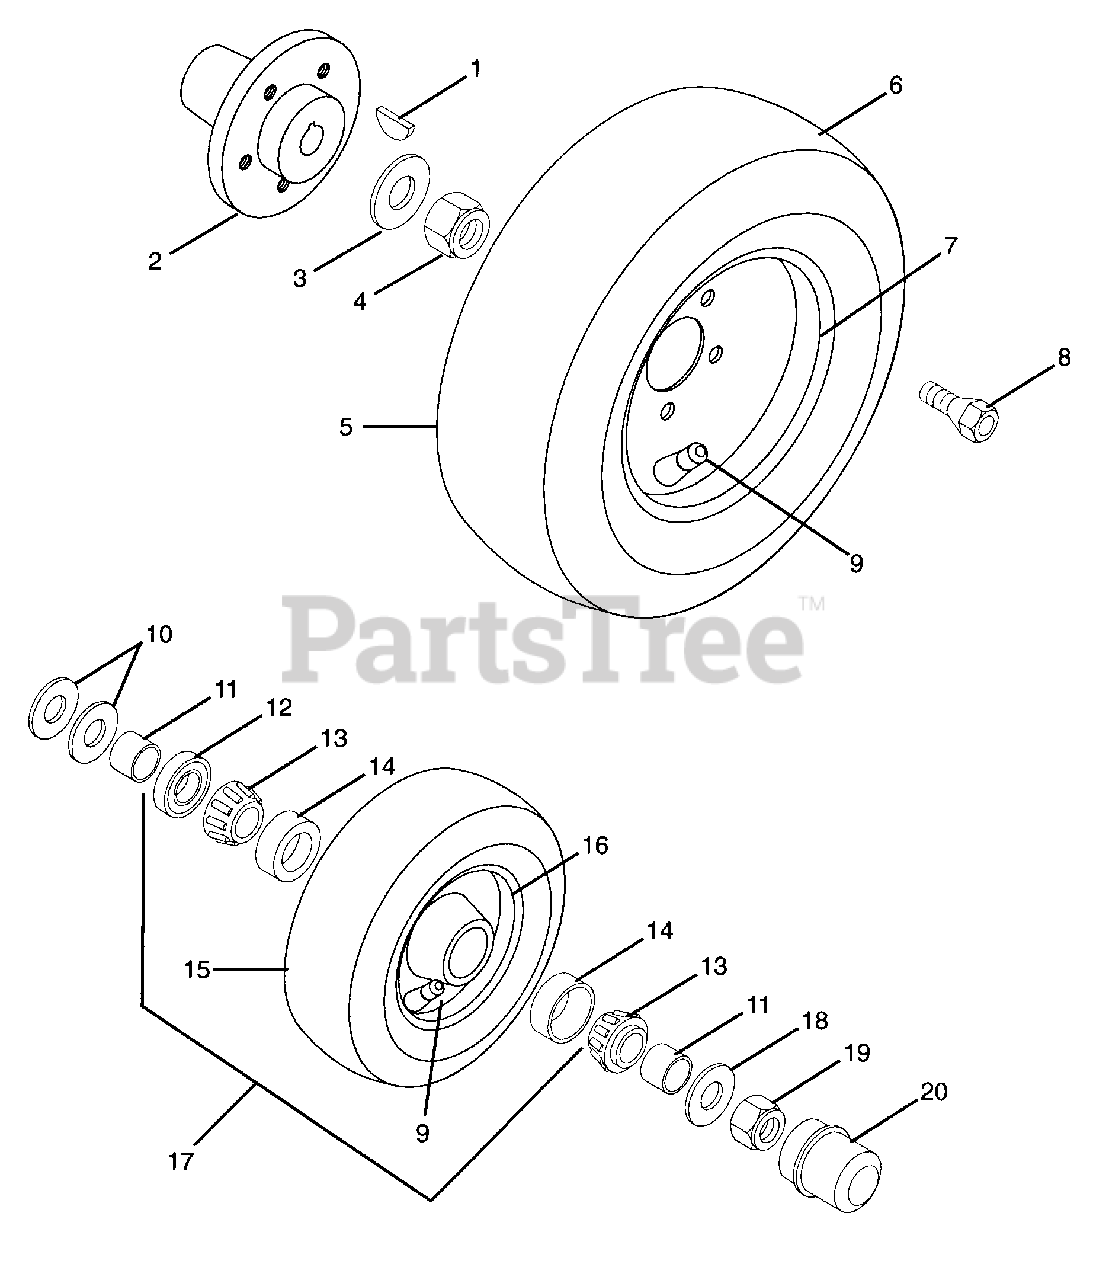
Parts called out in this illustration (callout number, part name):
1	Key-Woodruff .25 x 2.13
2	Hub-Tapered 4-Wheel
3	Washer-Flat-Steel .813 x 2.000 x .148
4	Nut-Locking-Center .75-10 Grade 2
5	Tire/Wheel Assembly 23 x 8.5-12
5	Tire/Wheel Assembly 23 x 10.50-12
6	Tire-Rear 23 x 8.50-12
6	Tire-Rear 23 x 10.50-12
7	Weldment-Rim
8	Bolt-Hex .44-20 x 1.00
9	Valve Stem Assembly
10	Washer-Flat-Steel .813 x 1.50 x .139
11	Spacer
12	Seal 1.206 x 1.785 x .468
13	Bearing/Cone .750 x .61
14	Bearing/Cup 1.781 x .475
15	Tire-Front 16 x 6.50-8
15	Tire-Front 16 x 7.50-8
16	Weldment-Rim
17	Tire/Wheel Assembly 16 x 6.5 x 8
17	Tire/Wheel Assembly 16 x 7.50-8
18	Washer-Flat-Steel .656 x 1.312 x .095
19	Nut-Locking-Center .625-11 Grade 2
20	Dust Cap
